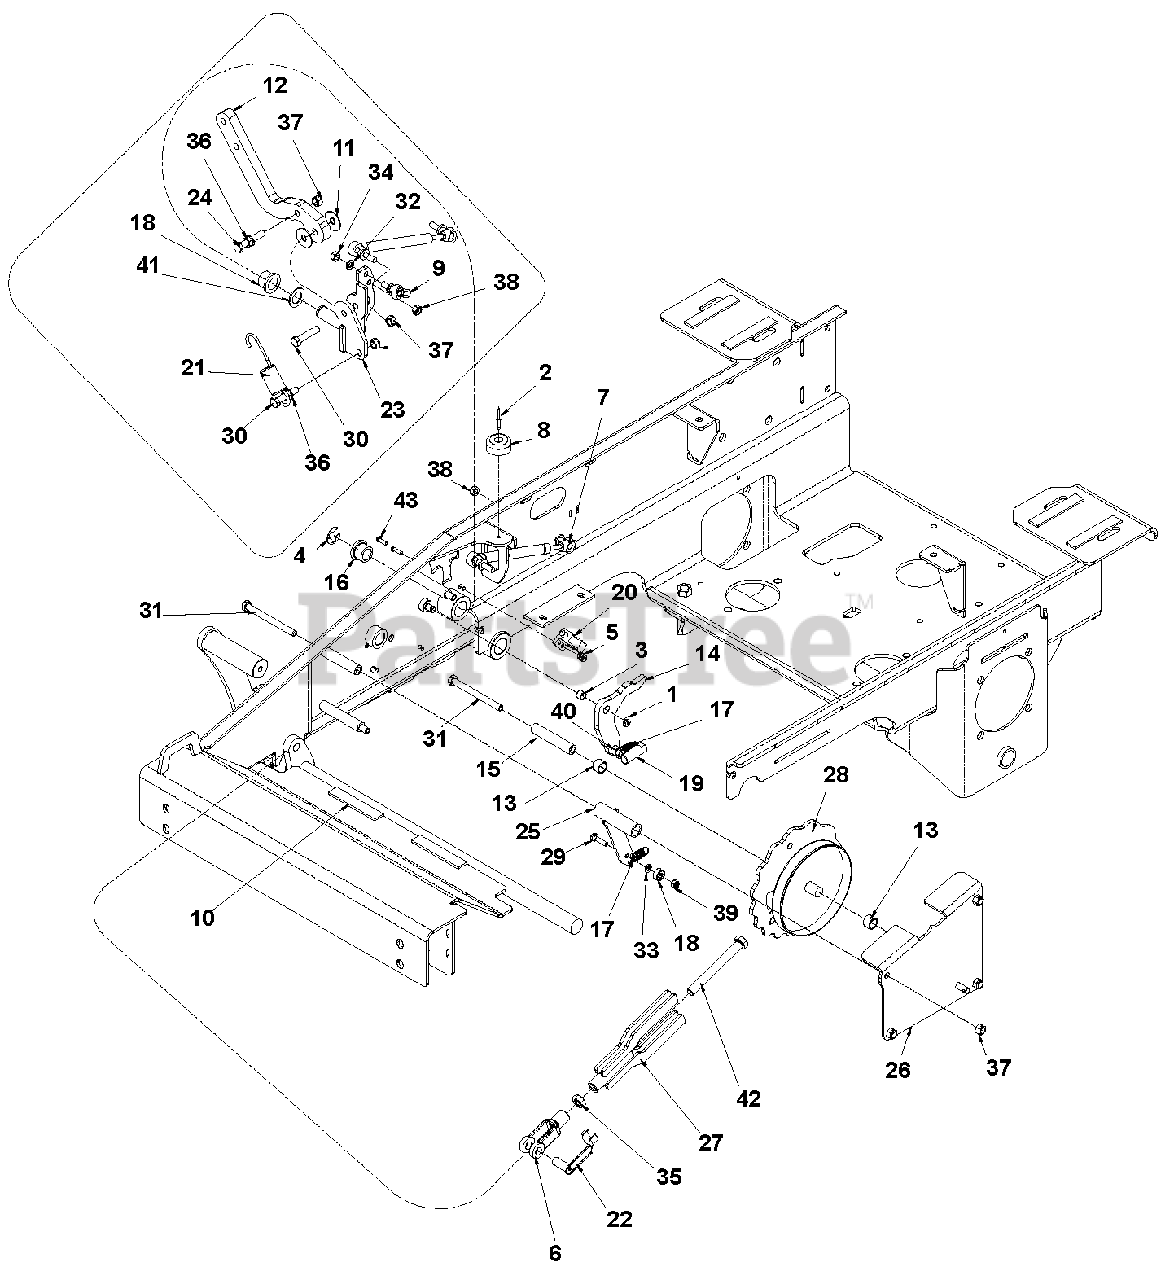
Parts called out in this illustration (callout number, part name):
1	E-Ring, .375 x .035
2	Rivet, 3/16 x .500 Pop
3	Bearing, Sleeve .377 x .503 x .375
4	E-Ring, .750 x .050
5	Nut, 10-24 KEPS
6	Yoke, Adjuctable 1/2-13
7	Dampener, Steering Control
8	Bumper, Rubber .625 x 1.50 DIA
9	Ball Joint, RH 5/16 FMAL W/STD
10	Foam, .125 x .750 x 4.00
11	Washer, .400 x 1.27 x .062 Nylon
12	Plate, Steering Control
13	Bearing, Sleeve .627 x .752 x .500
14	Plate, Brake Lever
15	Spacer, .63 x .385 x 3.250
16	Bearing, Flange .750 x 1.00 x .750
17	Spring, Extension .500 x .041 x 1.75 SS
18	Bearing, Ball .250 x .688 x 313
19	Ball Joint, 3/8 x 24
20	Switch, Plunger DP - N.O. - N.C.
21	Spring, Extension .980 x .162 x 4.00
22	Pin, Clevis Spring 1/2" Yoke
23	Weldment, LH Steering Control
24	Bolt, 3/8-16 x 2.00 HEX 5 FLTD
25	Weldment, HOC Index Arm
26	Weldment, HOC Cover
27	Weldment, HOC Link
28	Weldment, HOC Cam Control 400
29	Bolt, 1/4-20 x 1.00 HEX 5
30	Bolt, 3/8-16 x 1.75 HEX 5
31	Bolt, 3/8-16 x 4.00 HEX 5
32	Washer, .313 MED Spring Lock
33	Washer, M6 REG Flat
34	Nut, 5/16-24 STD HEX GR5
35	Nut, 1/2-13 Jam GR5
36	Lochnut, 3/8-16 Whiz
37	Locknut, 3/8-16 Crown
38	Locknut, M8-1.25 Crown
39	Locknut, 1/4-20 Nyloc
40	Nut, 3/8-24 STD HEX GR5
41	Bushing, MACH .750 x 1.25 x .075
42	Bolt, 1/2-13 x 4.50 HEX 8
43	Screw, 10-24 x .625 PAN PHL MAC
